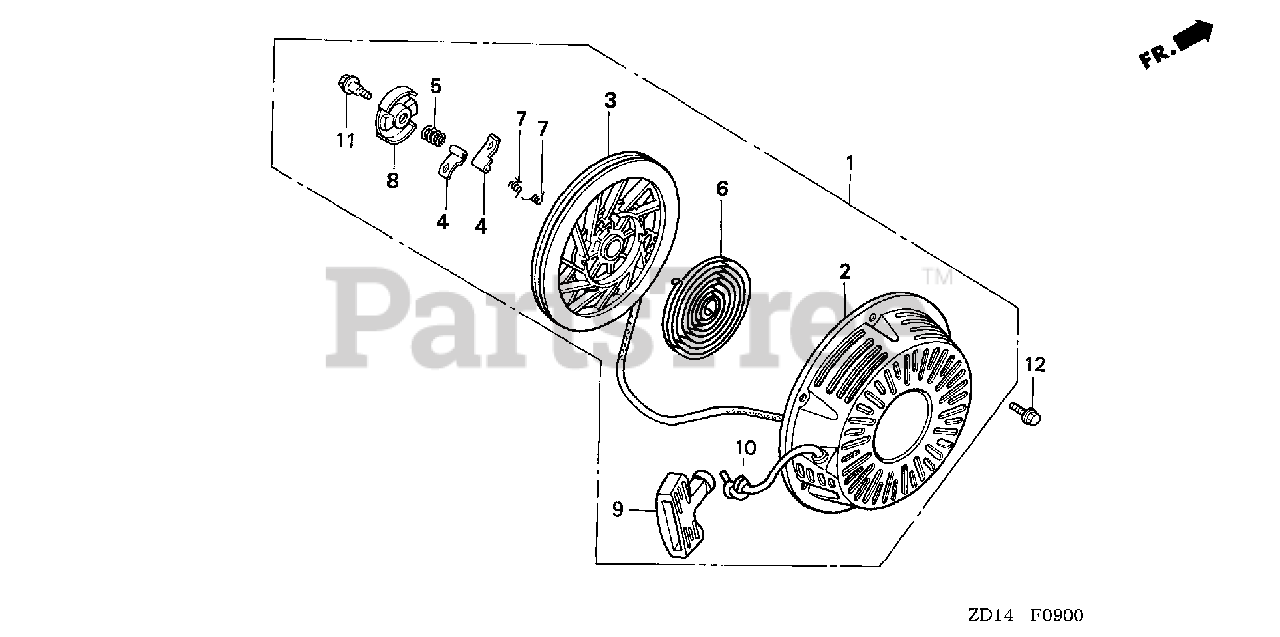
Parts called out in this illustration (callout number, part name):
1	STARTER ASSY., RECOIL *NH1* (BLACK)
2	CASE, RECOIL STARTER *NH1* (BLACK)
3	PULLEY, RECOIL STARTER
4	RATCHET, STARTER
5	SPRING, FRICTION
6	SPRING, STARTER RETURN
7	SPRING, RATCHET
8	RETAINER, SPRING
9	GRIP, STARTER
10	ROPE, RECOIL STARTER
11	SCREW, CENTER
12	BOLT, FLANGE (6X10)
